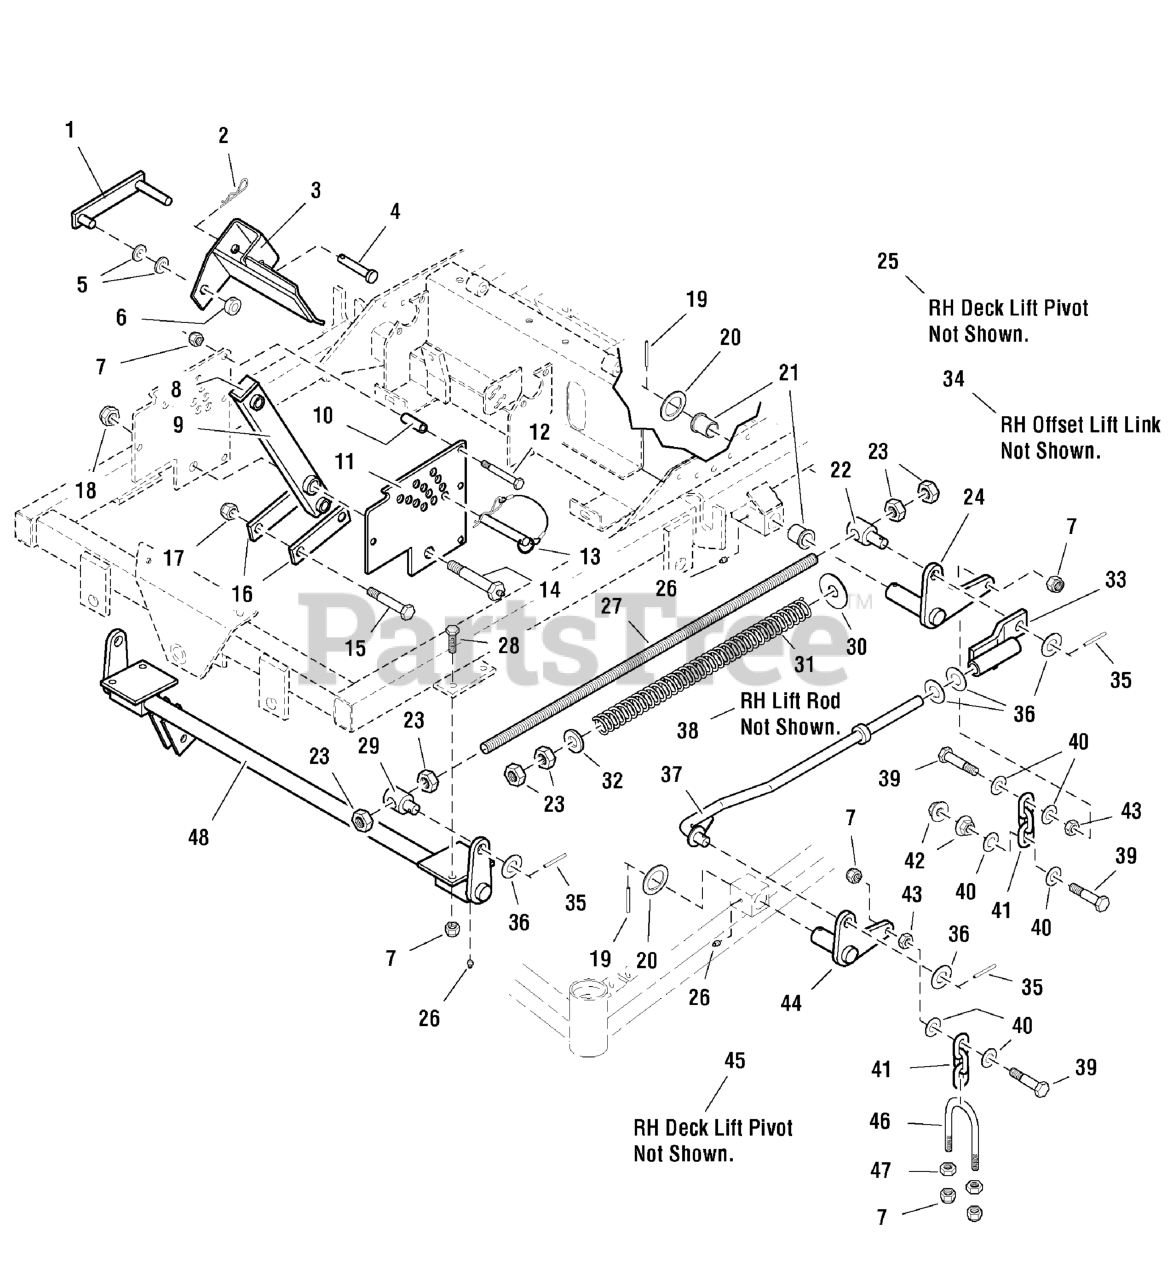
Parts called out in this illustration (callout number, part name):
1	DECK LIFT LOCK
2	HAIRPIN CLIP
3	WELD, DECK LIFT PEDAL
4	PIN, Clevis, 1/2 x 2-1/2
5	WASHER, 1/2 SAE
6	COLLAR, Split, 1/2
7	NUT, 3/8-16 HEX NYLON LOCK
9	ARM, Deck Lift Pivot
10	SPACER, .38 x .50 x 1.56
11	DECK HEIGHT PLATE
12	BOLT, 3/8-16 X 2-3/4" GD5 CZ
13	PIN, 1/2 x 3-1/2 w/ Lanyard
14	LIFT PIVOT BOLT
15	BOLT, 1/2-20 x 3
16	LINK, Deck Lift
17	NUT, Hex, Nylon Lock, 1/2-20
18	NUT, 5/8-11 Hex Jam Nylon Lock
19	PIN, Roll, 3/16 x 1-1/2
21	BUSHING, Flange
22	SPRING ROD PIVOT
23	NUT, 5/8-11 Hex
24	DECK LIFT PIVOT - LH
26	GREASE FITTING
27	SPRING ROD
28	BOLT, 3/8-16 X 1-1/4" GD5 CZ
29	SPRING ROD PIVOT
30	WASHER, 5/8" USS
31	SPRING, Deck Lift
32	SPACER, .63 x 1.06 x .23
33	DECK LIFT OFFSET LINK-LH
35	PIN, Spring, 3/16 x 1-1/4
36	WASHER, 5/8" SAE
37	DECK LIFT ROD-LH
39	BOLT, 3/8-16 X 1-3/4" GD5 CZ
40	WASHER, 3/8 SAE
41	CHAIN, 3 LINKS
42	NUT, 3/8-16 Hex Serrated Flange
43	NUT, 3/8-16 HEX JAM
44	DECK LIFT PIVOT-LH
47	NUT, 3/8-16 Hex
48	DECK LIFT SHAFT & MOUNT ASSEMBLY
